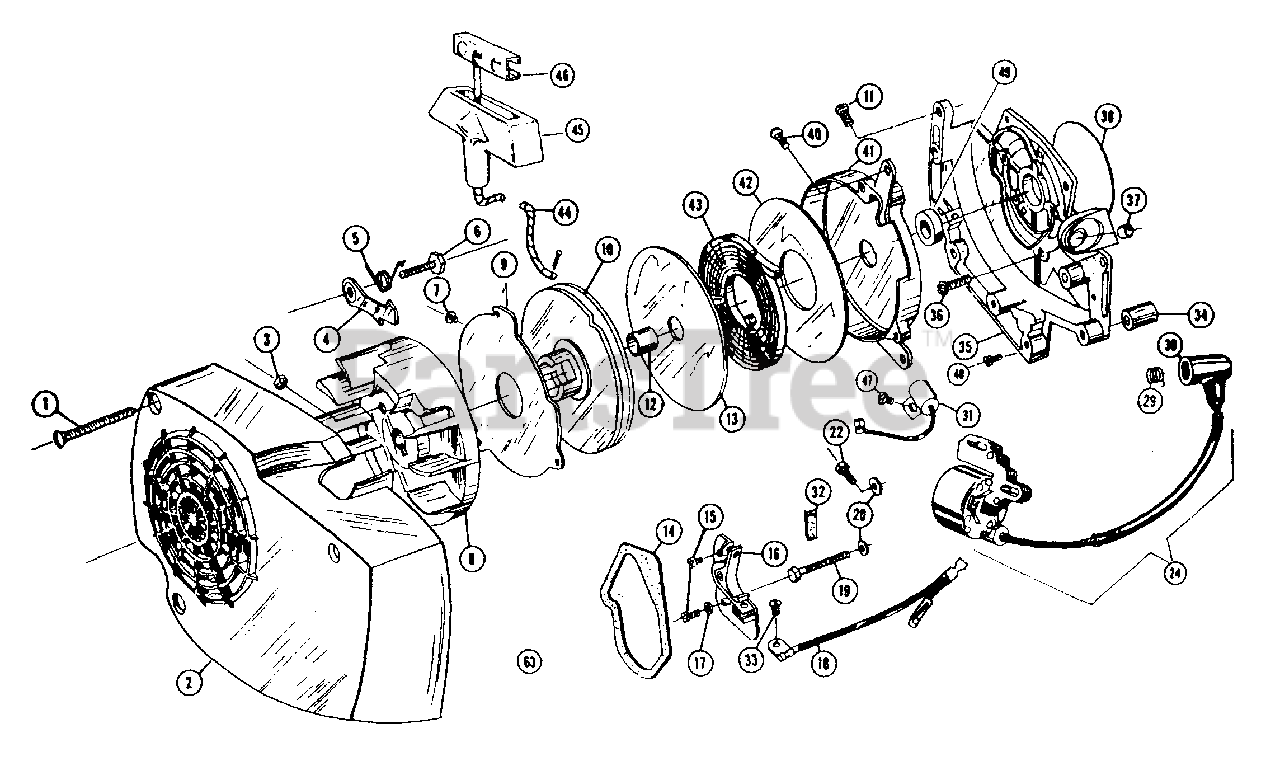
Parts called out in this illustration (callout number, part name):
1	Screw 10-24 x 2-7/16
2	Housing - Fan
3	Nut - Starter Dog
4	Dog - Starter
5	Spring - Starter Dog
6	Bolt - Starter Dog
7	Screw-Starter
8	Flywheel
9	Cover - Starter
10	Starter Pulley Ass'y. w/Bearing
12	Bearing -Starter Pulley
13	Disc - Starter - Top
14	Gasket - Points Cover
16	Breaker Assembly
17	Washer No. 8
18	Lead - To Coil
20	Washer No. 8
22	Screw-Coil to Brg. Carrier
24	Coil - Terminal Ass'y.
29	Connector
30	Boot-Spark Plug Wire
31	Condenser
32	Wick - Oiler
33	Screw - Breaker Lead
35	Bearing Carrier - w/Rope Bushing
36	Screw - Carrier Mount
37	Bushing - Starter Rope
38	O'Ring
40	Screw - Starter Mount
41	Starter Housing
42	Disc - Starter Bottom
43	Spring - Recoil
44	Rope - Assembly
45	Handle - Starter
46	Anchor - Handle
47	Screw - Condenser Mount
48	Screw - Cyl. Shroud to Bearing Carrier
49	Seal
